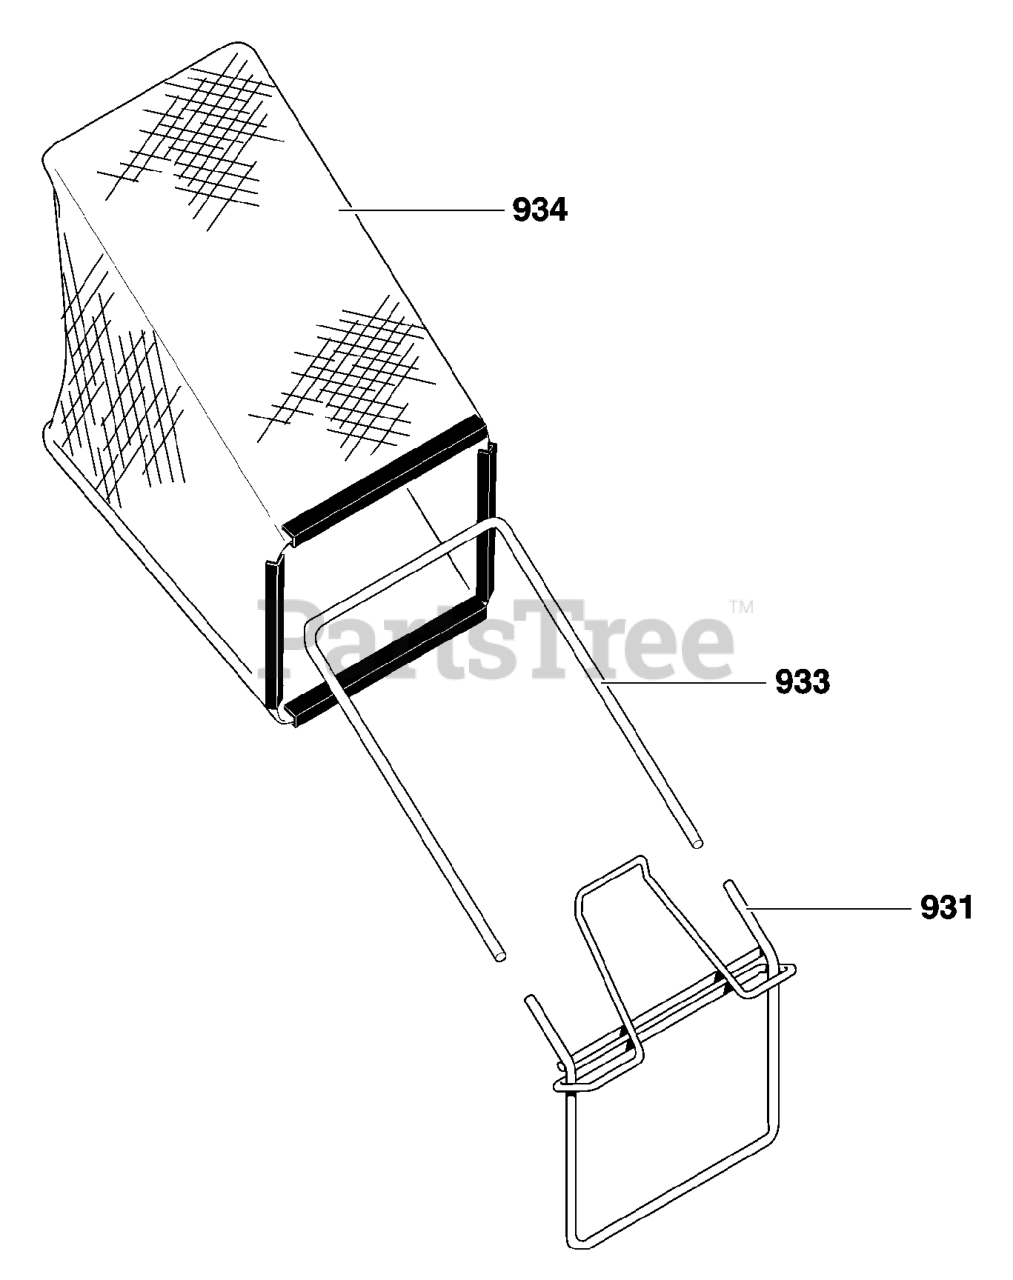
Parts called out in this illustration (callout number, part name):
931	ASSY, BAG FRAME
933	FRAME, BAG TOP
934	BAG, 21"
